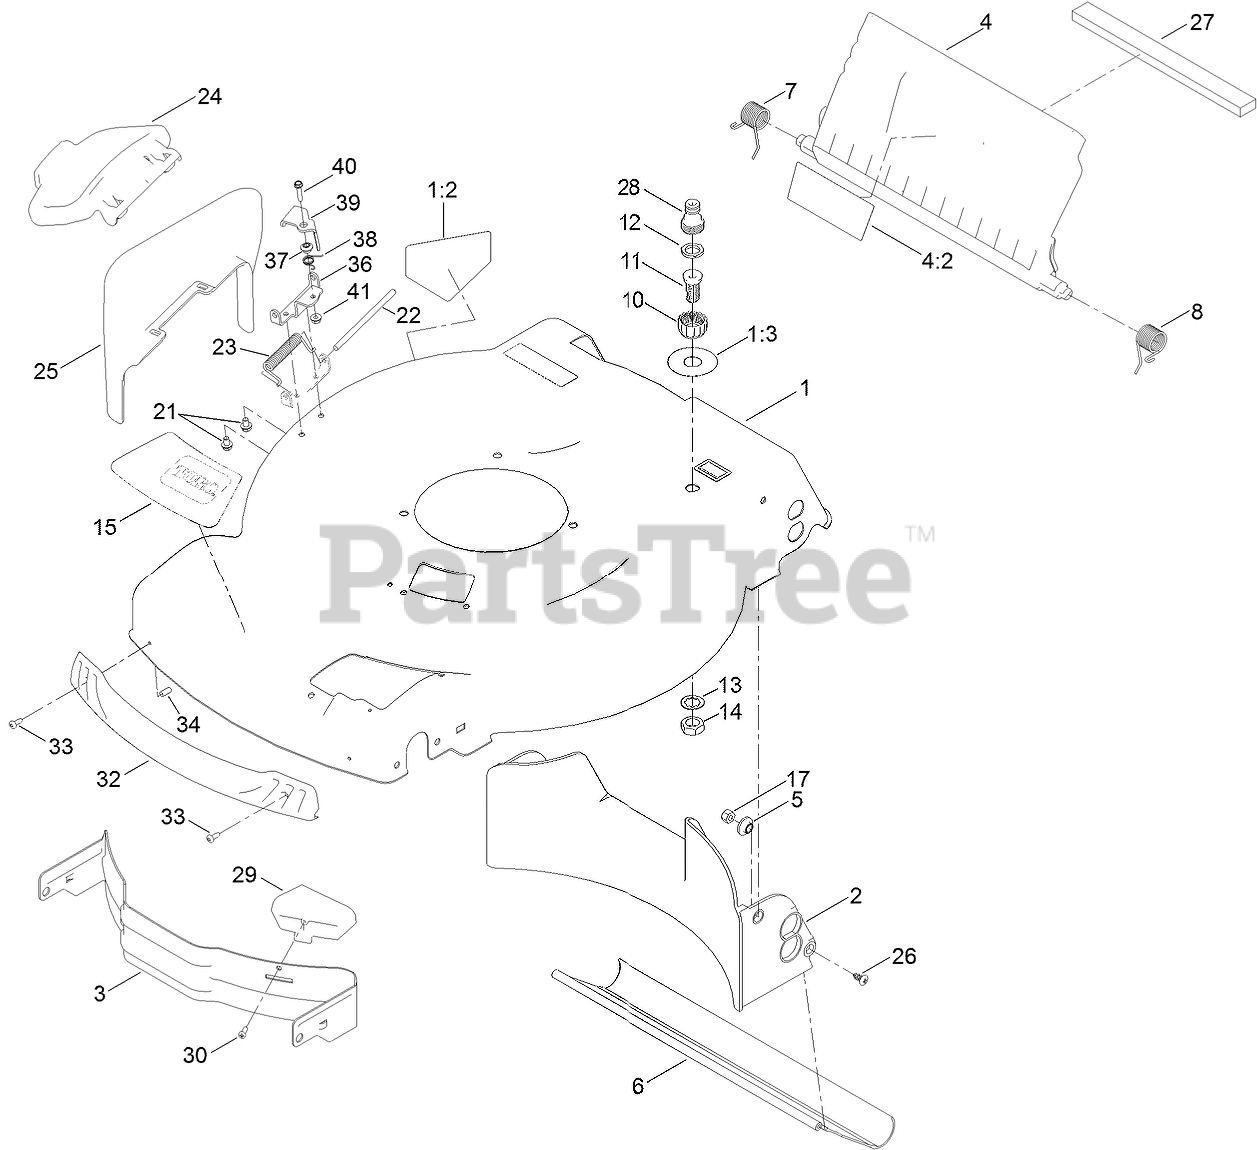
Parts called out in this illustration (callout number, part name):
1	HOUSING ASM
1:2	DECAL-DANGER
1:3	DECAL-QUICK WASH
2	BAFFLE-REAR
3	BAFFLE-FRONT
4	REAR DEFLECTOR ASM
4:2	DECAL-WARNING
5	WASHER-STEPPED, BAFFLE
6	SHIELD-TRAILING
7	SPRING-TORSION
8	SPRING-TORSION
10	COUPLING-HOSE, WASHOUT PORT
11	PORT-WASHOUT
12	WASHER-SEAL, WASHOUT PORT
13	WASHER-LOCK
14	NUT-JAM
15	DECAL-DECK
17	NUT-LOCK, NI
21	SCREW-HWH
23	SPRING-TORSION
24	DEFLECTOR-DISCHARGE, SIDE
25	CHUTE-DISCHARGE, SIDE
26	SCREW-PTH
27	FOAM-SEAL
28	ADAPTER-CONNECT, QUICK
29	KICKER-FRONT
30	SCREW-PLASTIC, PPH
32	BUMPER
33	SCREW-FORMING, THREAD
34	CAP-PLUG
36	BRACKET-LOCKOUT
37	SPACER
38	SPRING-TORSION
39	LEVER-LOCKOUT
40	SCREW-HWH
41	NUT-HEX FLANGE
